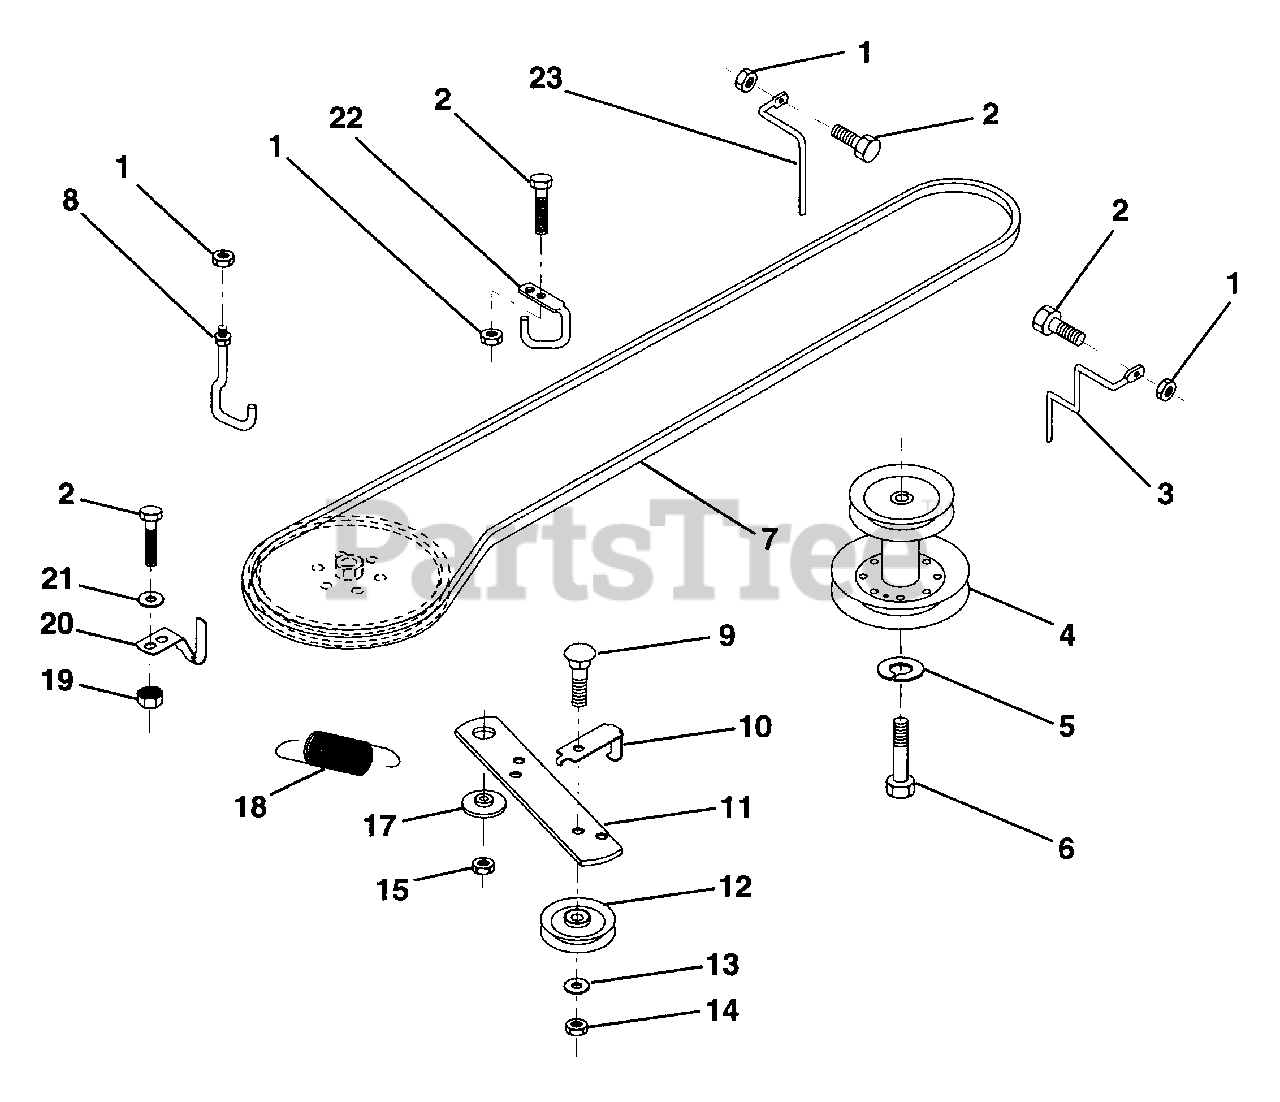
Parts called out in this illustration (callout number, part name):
1	Nut, Crownlock 5/16-18
2	Bolt, Hex Hd. 5/16-18 UNC x 3/4
3	Keeper, Mower Drive Belt, R.H.
4	Pulley, Engine
5	Washer, Lock 7/16
6	Bolt, Hex, Fin. 7/16-20
7	Traction, V-Belt, Drive
8	Keeper, T/A, Ground Drive Belt
9	Bolt, Carriage 3/8-16 UNC x 1-1/2
10	Keeper, Ground Drive, Belt, Idler
11	Clutch Arm, Ground Drive
12	Idler, Flat
13	Washer 13/32 x 13/16 x 16 Ga.
14	Nut, Centerlock 3/8-16 UNC
15	Nut, Crownlock 3/8-16 UNC
17	Spacer, Retainer
18	Spring Extension
19	Nut, Hex, Keps 5/16-18 UNC
20	Keeper, T/A, Ground Drive Belt
21	Washer 11/32 x 5/8 x 16 Gauge
22	Keeper, Frame, Ground Drive Belt
23	Keeper, Mower Drive Belt, L.H.
